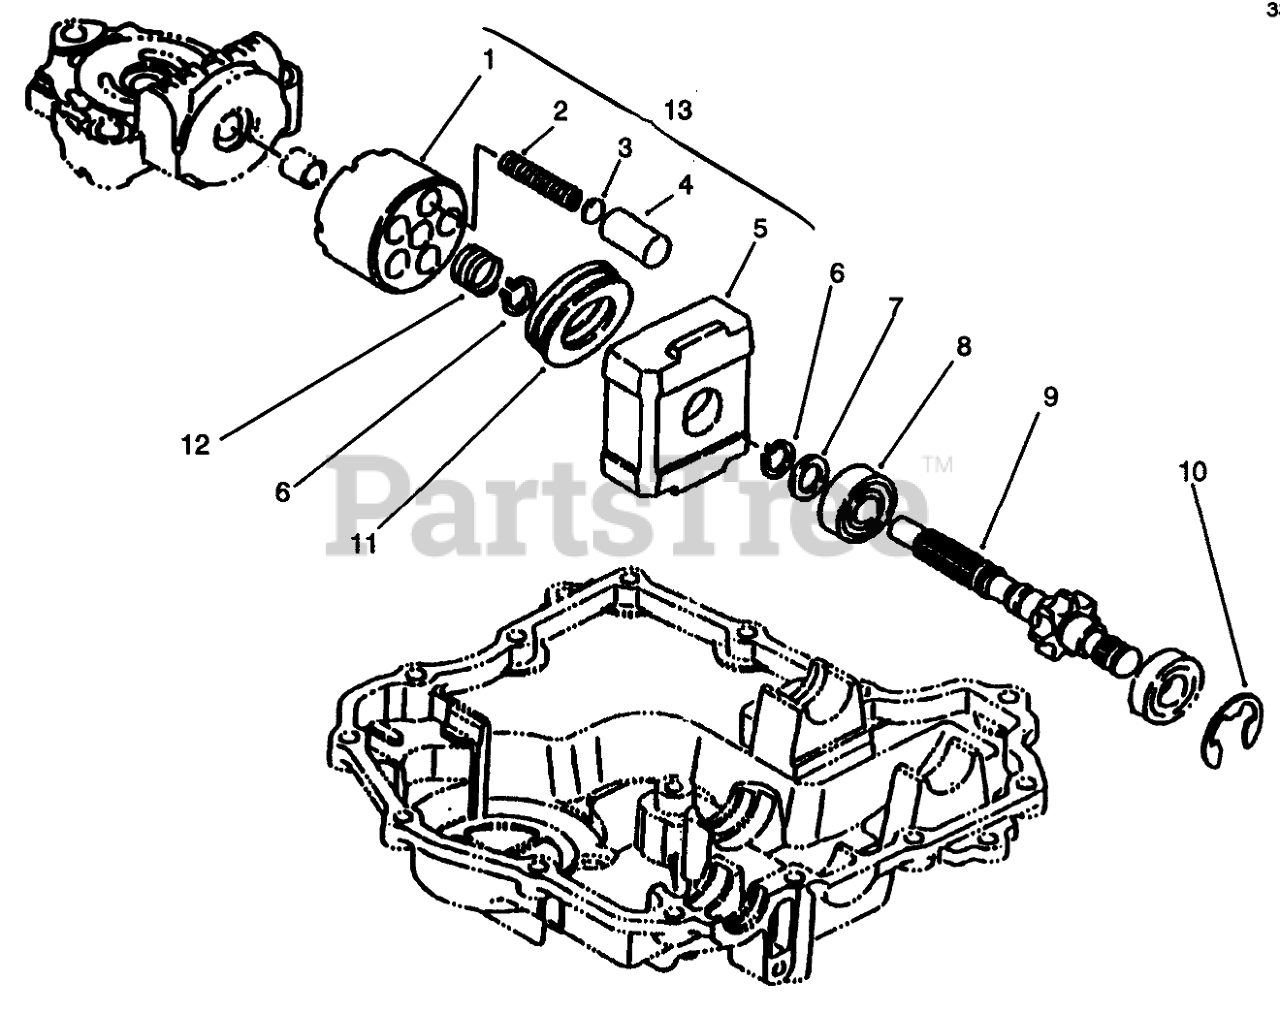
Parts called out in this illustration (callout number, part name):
1	Block-Cylinder
3	Washer
5	HOUSING
6	RING-SNAP
7	WASHER
8	BEARING-BALL
9	SHAFT - MOTOR
10	E-RING
11	BEARING-THRUST
13	ASM - CYCLINDER INC 6-9
